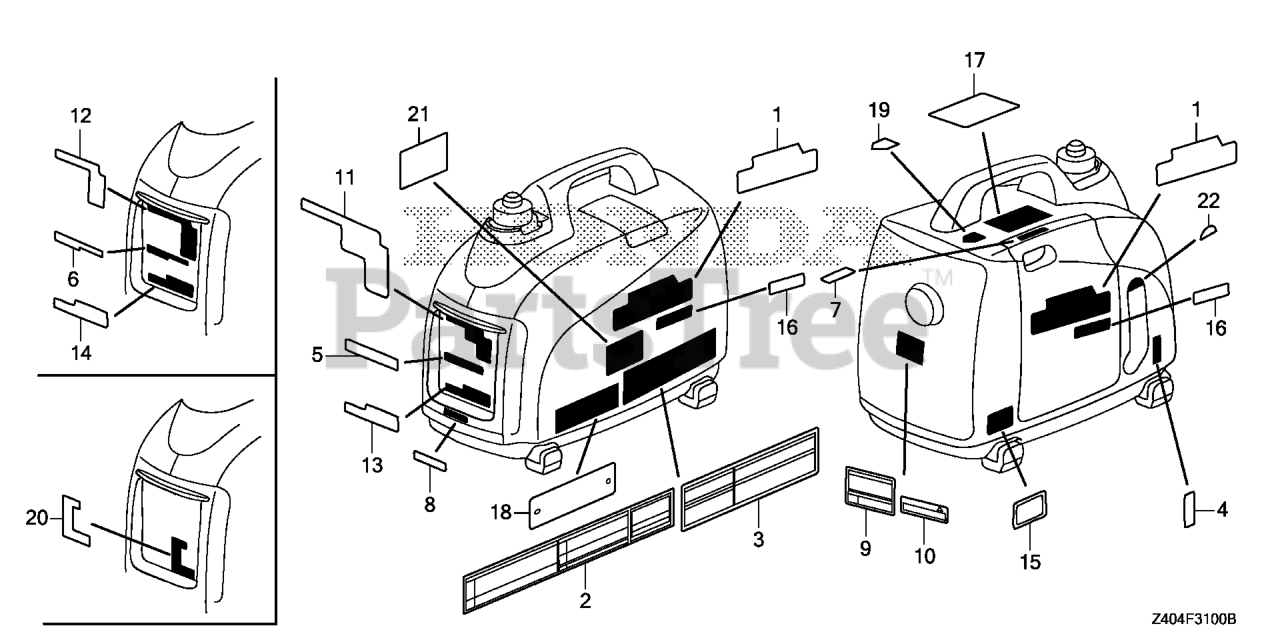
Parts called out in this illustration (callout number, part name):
1	EMBLEM (EU1000i)
2	MARK, CAUTION
4	MARK, ENGINE SWITCH
7	MARK, CHOKE
8	MARK, HONDA
9	MARK, EX. WARNING (E)
15	MARK, OIL CAUTION
17	MARK, CPSC (CO CAUTION)
19	MARK, DIRECTION
20	MARK, INDICATOR
21	LABEL, SHUTOFF CAUTION
22	LABEL, MASKING
